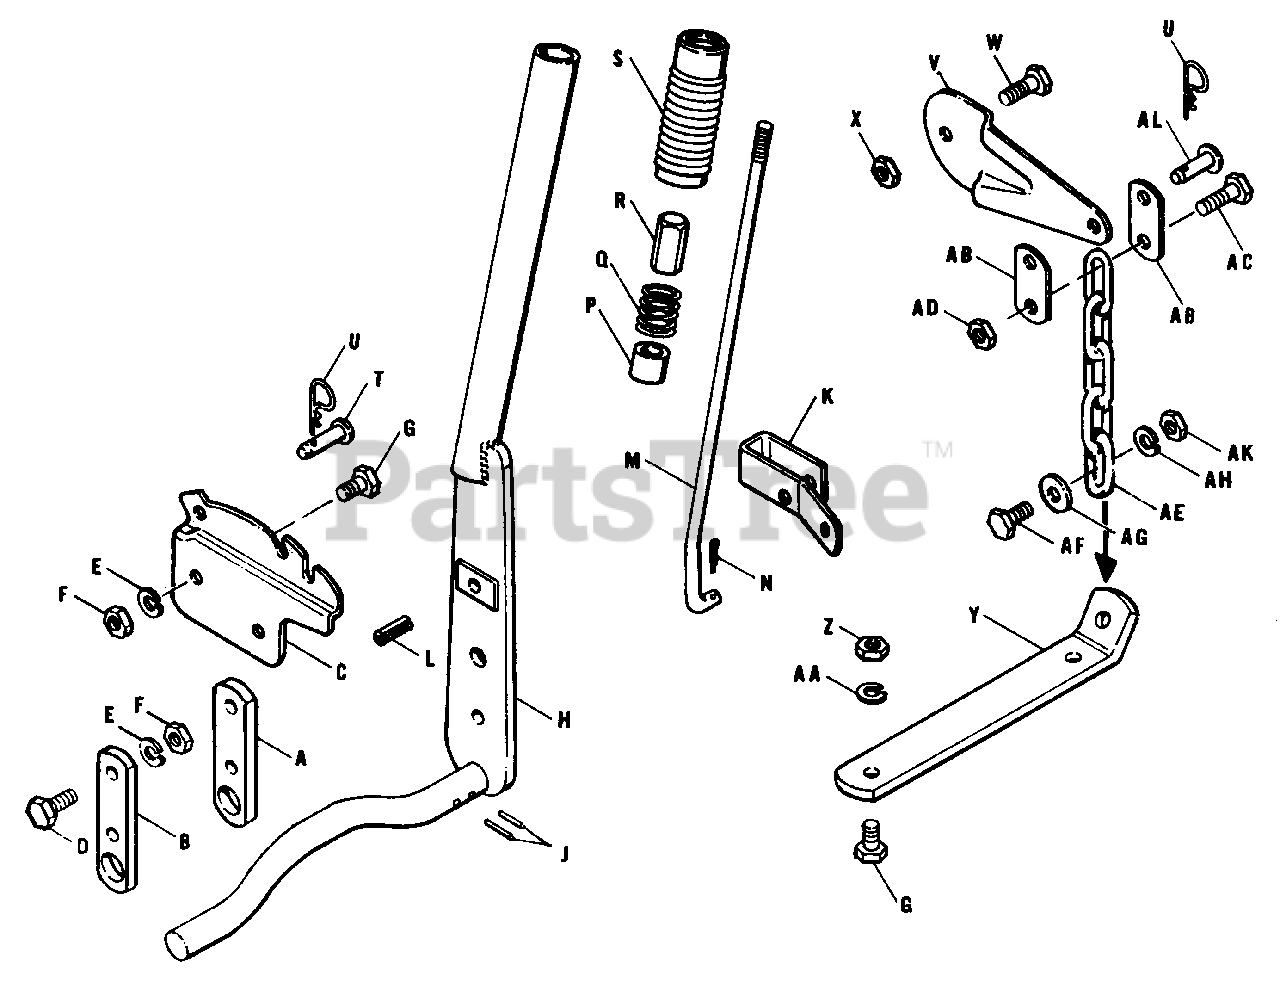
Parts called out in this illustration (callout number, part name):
A	R.H. Bearing Bar
B	L.H. Bearing Bar
C	Lift Lever Quadrant
D	Hex Cap Screw 3/8-16 x 1"
E	Lock Washer 3/8"
F	Hex Nut, Full 3/8-16
G	Hex Cap Screw 3/8"-16 x 3/4"
H	Lift Lever Assembly
J	Roll Pin 3/16" diam. x 1"
K	Lift Lever Latch
L	Roll Pin 3/8" diam. x 1"
M	Lift Lever Latch Rod
N	Cotter Pin 3/32" diam. x 3/4" lg.
R	Thumb Button
S	Handle Grip
U	Spring Clip
V	Mower Lift Lever
W	Hex Cap Screw 3/8"-16 x 7/8"
X	Hex Nut, Full Lock, 3/8"-16
Y	Lift Bar (Use On No. 442 Mower Only)
Z	Hex Nut, Full 3/8"-16
AA	Lock Washer 3/8"
AB	Mower Lift Link
AC	Hex Cap Screw 3/8"-16 x 1"
AD	Hex Nut, Full Lock, 3/8"-16
AE	Chain
AF	Hex Cap Screw 3/8"-16 x 1"
AG	Plain Washer 3/8"
AH	Lock Washer 3/8"
AK	Hex Nut, Full 3/8"-16
